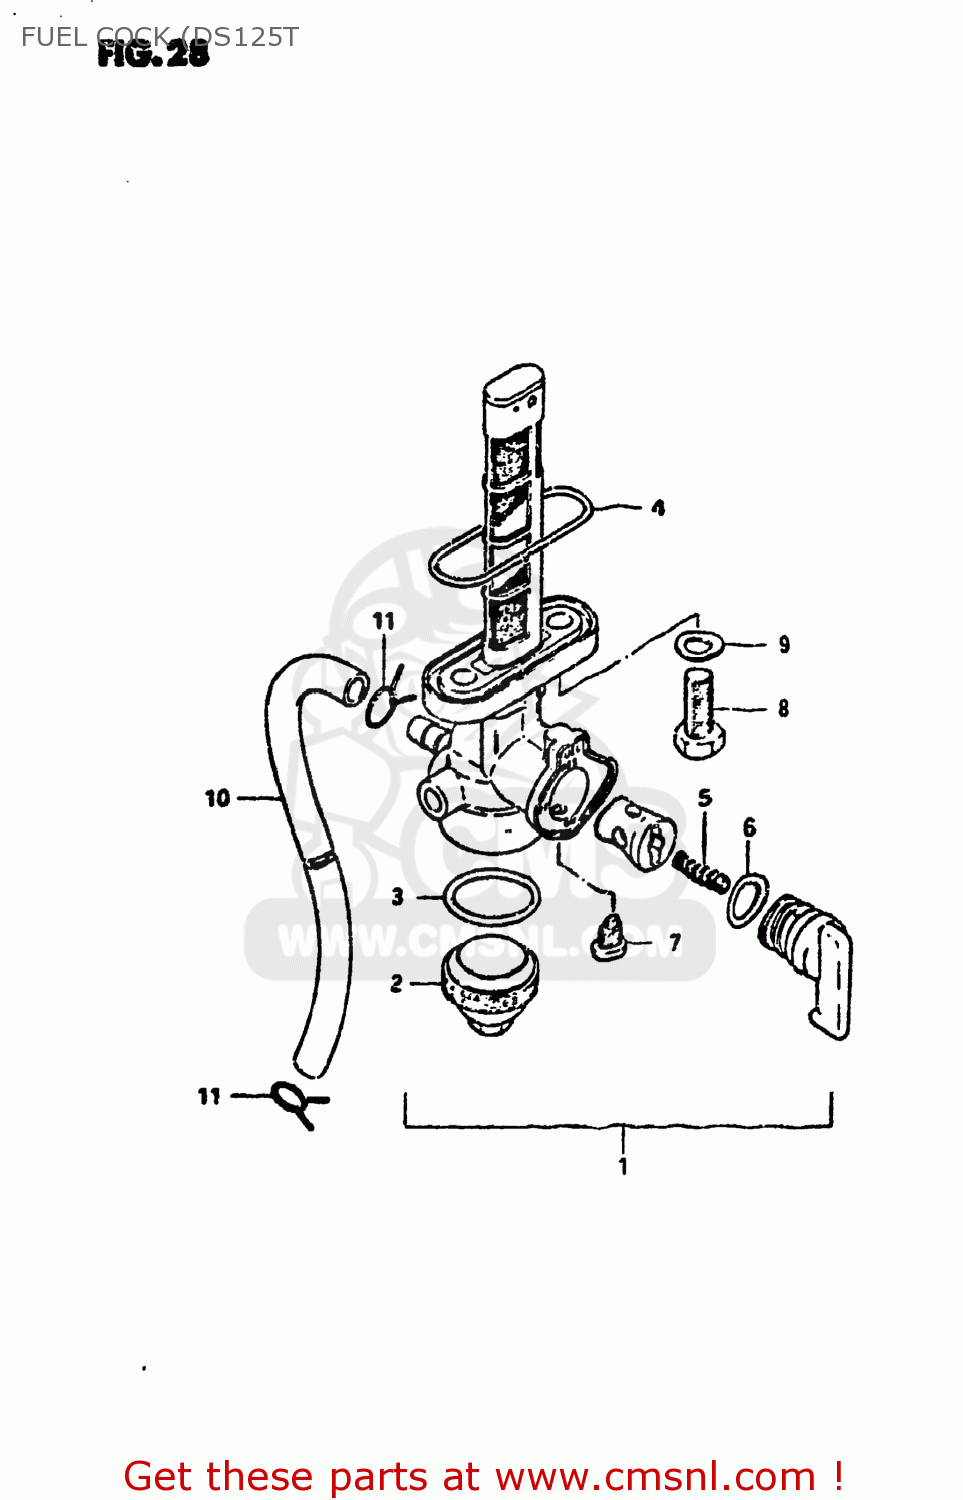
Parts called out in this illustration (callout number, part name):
1	COCK ASSEMBLY,FUEL
2	CUP,STRAINER
3	GASKET,FILTER (NAS)
4	O RING,FUEL COCK
5	SPRING
6	O-RING
7	SCREW
8	BOLT(6X20)
9	GASKET
10	HOSE
11	CLIP
